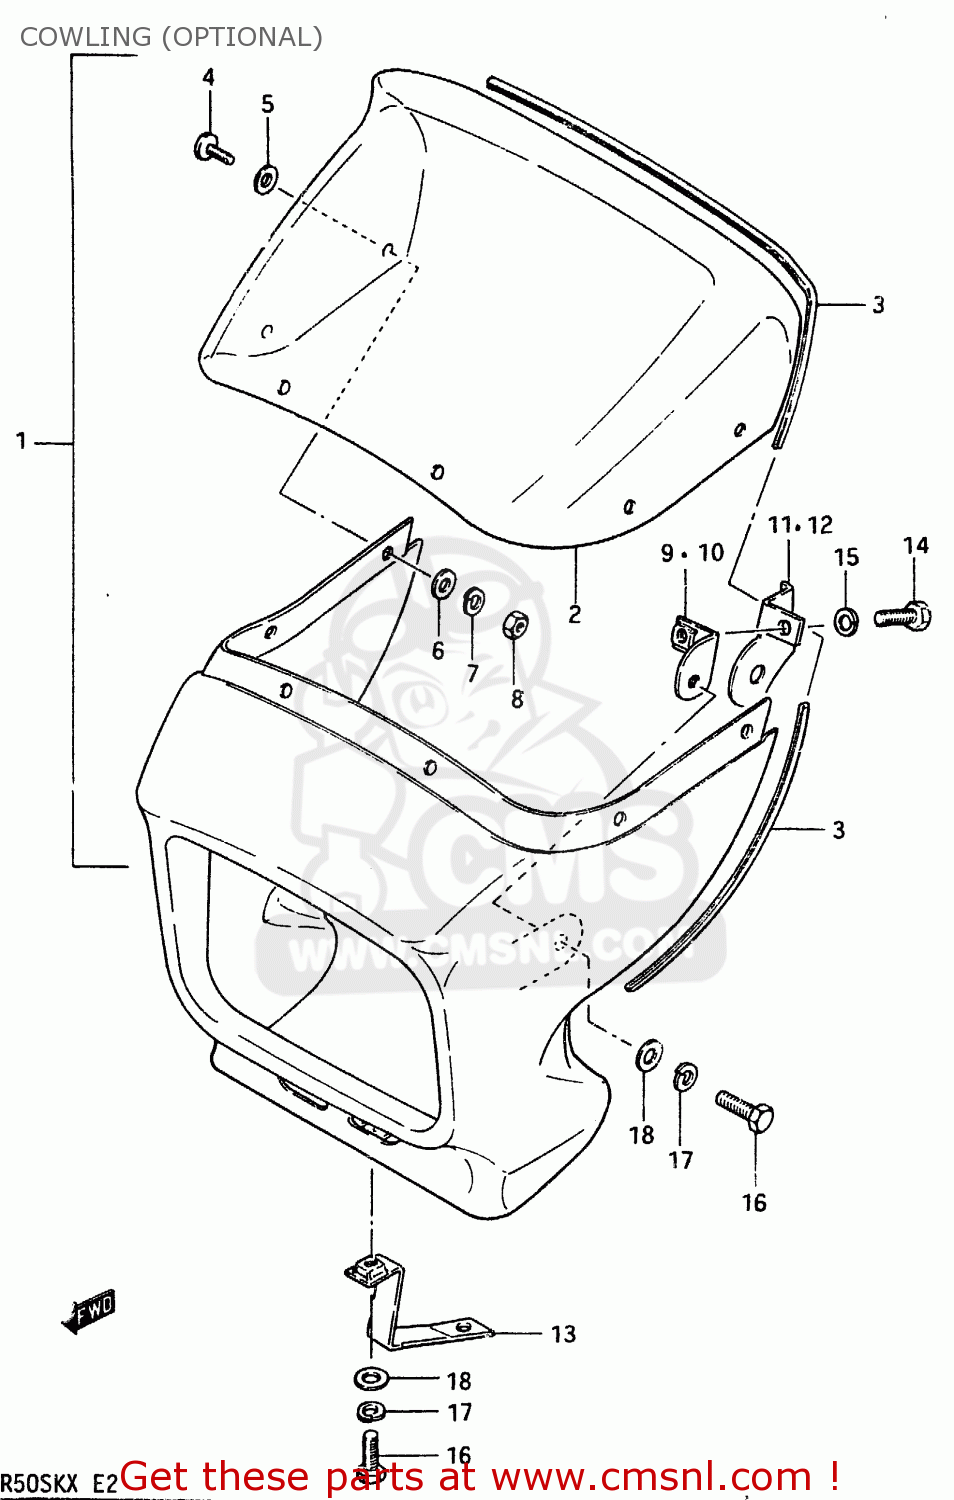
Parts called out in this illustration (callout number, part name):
1	COWLING ASSY
2	WINDOW,COWLING
3	MOULDING, WINDOW
4	SCREW M5X12 DIN 7985/N
5	CUSHION
6	WASHER
7	LOCK WASHER
8	NUT
9	BRACE, RH (L:19)
10	BRACE,COWLING LH
11	BRACKET, FITTING RH
12	BRACKET, FITTING LH
13	BRACKET, LOWER
14	BOLT
15	LOCK WASHER
16	BOLT, UPPER
17	LOCK WASHER
18	WASHER (6.5X18X1.6)
